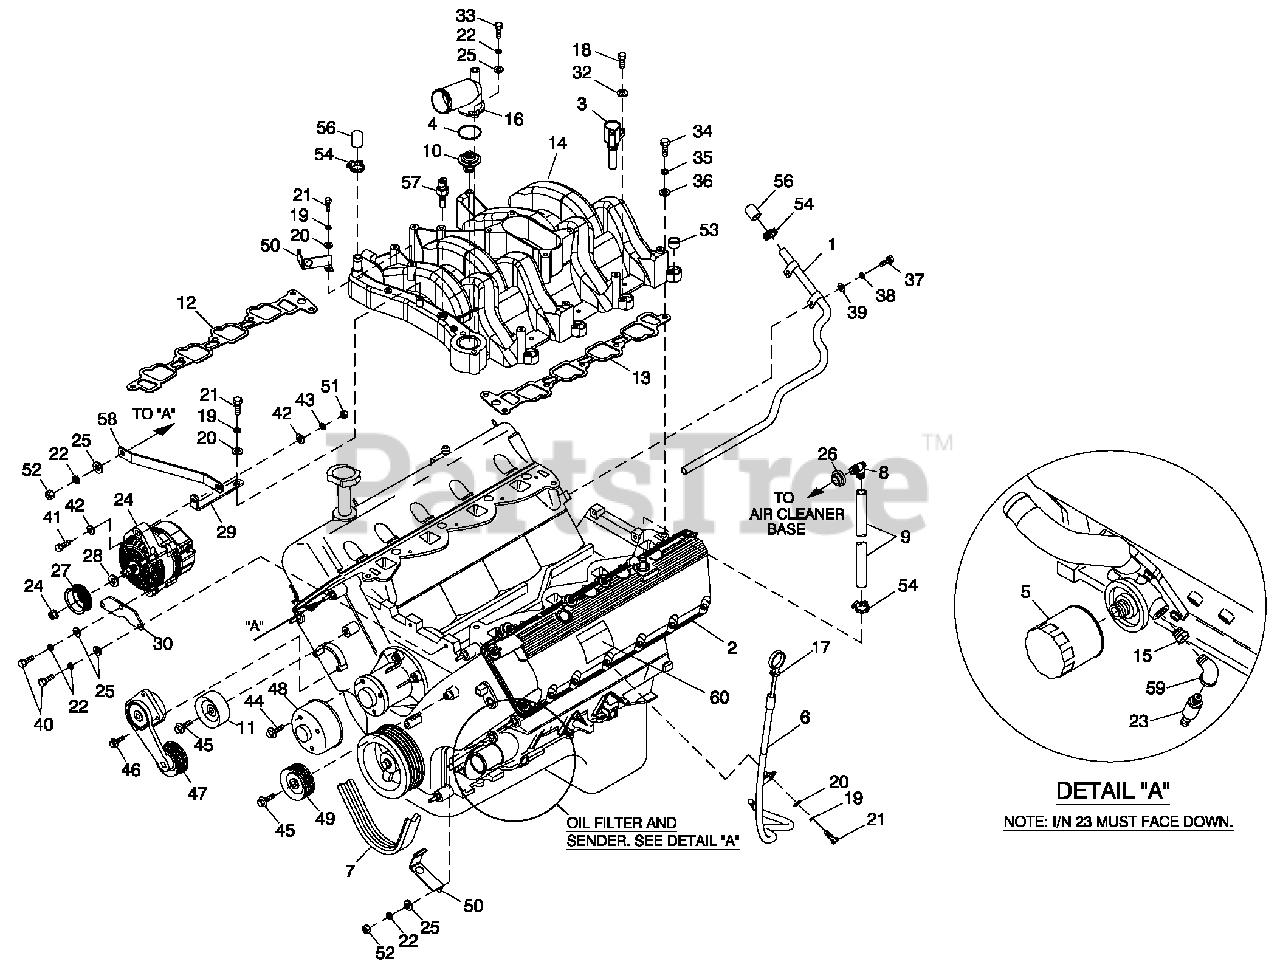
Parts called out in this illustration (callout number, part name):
1	TUBE HEATER WATER
2	ENGINE 5.4L FORD
3	IGNITION COIL ASSY FORD
4	GASKET THERMOSTAT HOUSING FORD
5	OIL FILTER FORD V-10 ENGINE
6	TUBE OIL LEVEL INDICATOR FORD
7	BELT SERPENTINE 65.0" (1800 RPM)
8	BARBED EL 90 3/4 PLASTIC
9	HOSE 3/4 ID SAE-30R2 (16.75"LG)
10	THERMOSTAT ASSY FORD
11	PULLEY FAN BELT FORD
12	GASKET INTAKE MANIFOLD RIGHT
13	GASKET INTAKE MANIFOLD LEFT
14	INTAKE MANIFOLD 5.4L (PLASTIC)
15	BSHG R D C R H E X1/4 TO 1/8
16	CONNECTION W ATER OUTLET FORD
17	REWORK DIPSTICK 5.4L 27.75"
18	SCREW H H C M 5-0.8X 25 G8.8
19	WASHER LOCK M6-1/4
20	W ASHER FLAT 1/4 ZINC
21	SCREW H H C M 6-1.0X 20 G8.8
22	W ASHER LOCK M8-5/16
23	SENDER OIL PRESSURE 1/8"NPT
24	ALTERNATOR DC W/OUT PULLEY
25	W ASHER FLAT 5/16 ZINC
26	GROMMET
27	PULLEY 80 OD DC ALTERNATOR (1800RPM)
28	SPACER DC ALTERNATOR PULLEY
29	BRKT DC ALTERNATOR UPPER
30	BRKT DC ALTERNATOR LOWER
32	W ASHER FLAT M5
33	SCREW H H C M 8-1.25X 90 G8.8
34	SCREW H H C M 8-1.25X 50 G8.8
35	W ASHER LOCK M8-5/16
36	W ASHER FLAT 5/16-M8 ZINC
37	SCREW H H C M 10-1.5X 20 G8.8
38	W ASHER LOCK M10
39	W ASHER FLAT 3/8-M10 ZINC
40	SCREW H H C M 8-1.25X 20 G8.8
41	SCREW HHC M10-1.5 X 45 G8.8 FT
42	W ASHER FLAT 3/8-M10 ZINC
43	W ASHER LOCK M10
44	SCREW WP PULLEY M8-1.25X 19
45	BOLT HEX FL HD M 8-1.25X 28
46	BOLT HEX FL HD M 8-1.25X 31
47	TENSIONER ENG. AUTOMATIC BELT
48	PULLEY W ATER PUMP FORD (1800RPM)
49	PULLEY GROOVED ENGINE IDLER
50	BRACKET SIGNAL CONDITIONER
51	NUT HEX M 10-1.5G 8Y E LC H R
52	NUT HEX M 8-1.25G 8Y E LC H R
53	PLUG EXPANSION 14 OD
54	CLAMP H O SE#10.56-1.06
56	CAP RUBBER
57	TEMPERATURE SENDER, DELPHI
58	BRACKET DC ALT STABILIZER
59	ELBOW 90D STREET 1/8
60	DECAL EPA STATIONARY EMERGENCY
